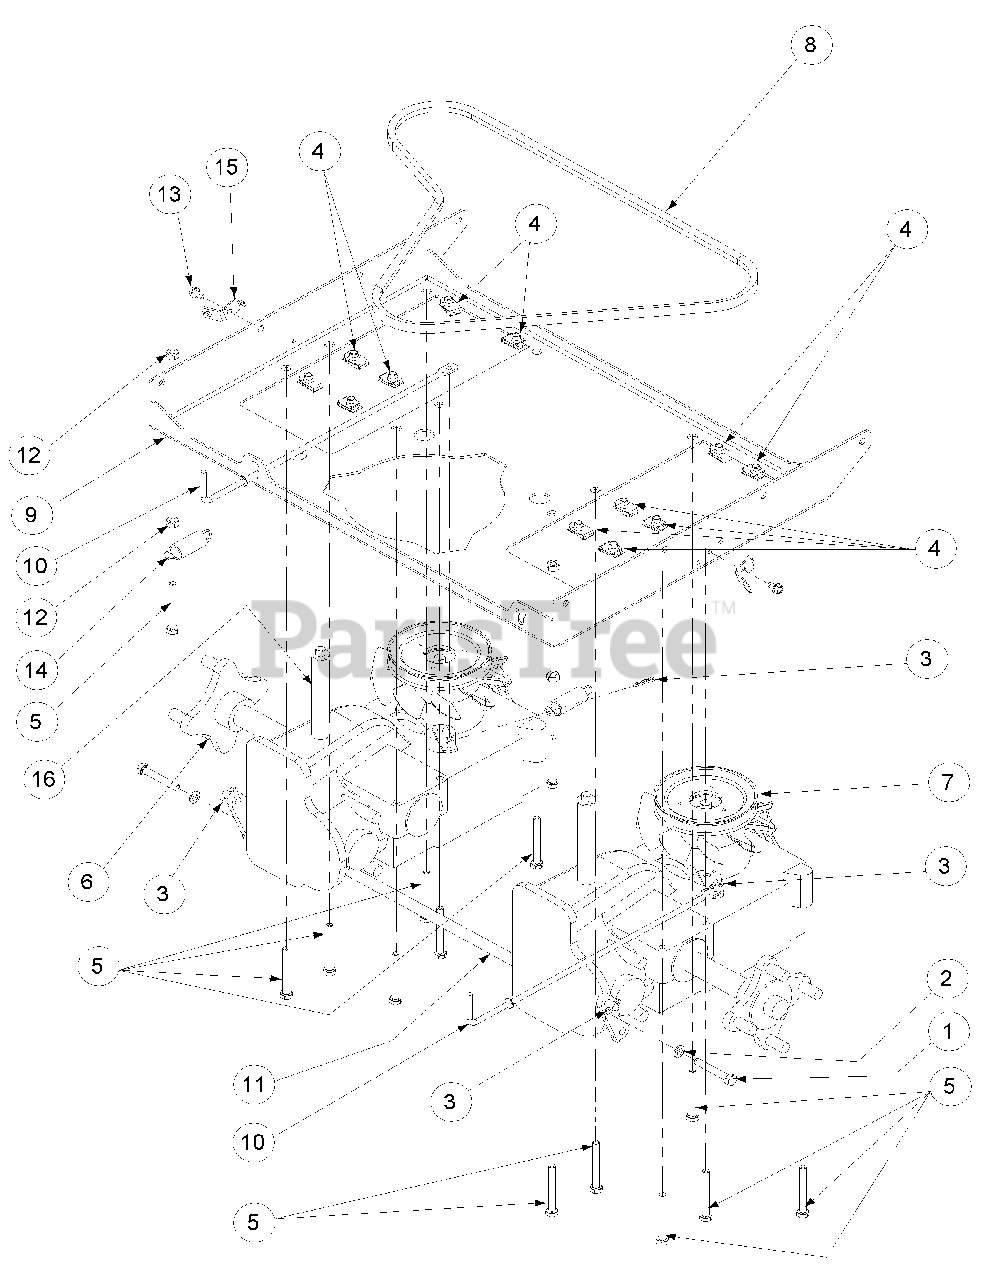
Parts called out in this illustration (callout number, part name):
1	Hex Cap Screw, 5/16-18 x 2.0
2	Flat Washer, .320 ID x .591 OD
3	Cotter Pin, .072 x 1.12 Lg
4	U-Nut, 5/16-18
5	Hex Cap Screw, 5/16-18 x 2.5
6	IZT Transmission, Left Hand
7	IZT Transmission, Right Hand
8	V-Belt, 56.00
9	Transmission Mounting Bracket
11	Transmission Brace Tube
12	Nut, 5/16-18
13	Screw, 1/4-20 x 1/2
14	Extension Spring, .438 OD x 2.50
15	Brake Cable Mounting Bracket
16	Hose, 1/2 Dia. x 4" Long
